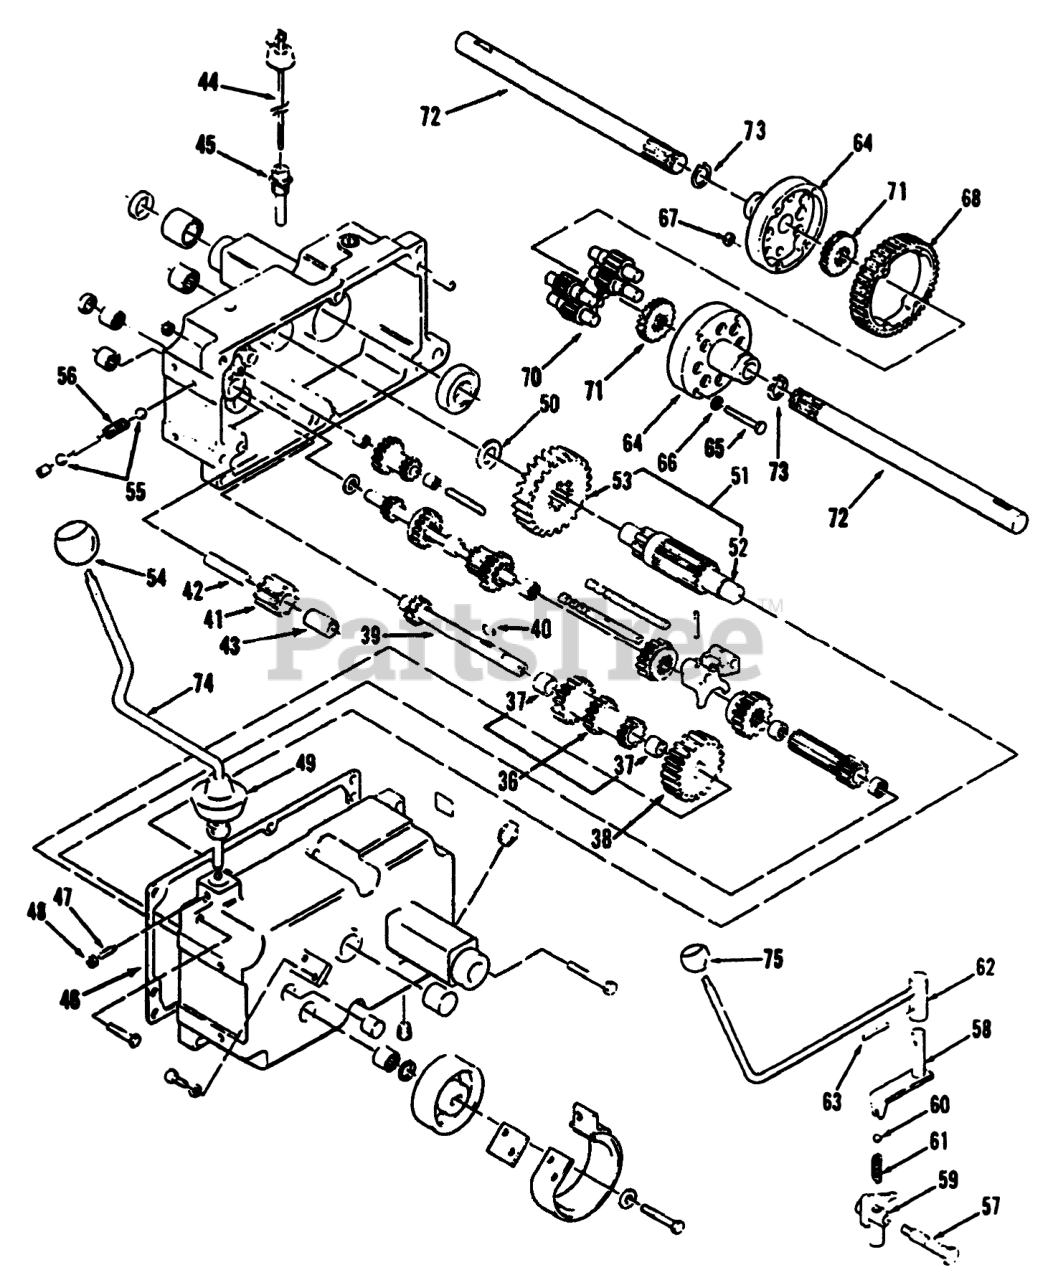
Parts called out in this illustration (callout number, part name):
36	GEAR-CLUSTER
37	BUSHING-BRONZE
38	GEAR-CLUSTER SHAFT
39	Shaft-Cluster
40	KEY-WOODRUFF
41	GEAR/BUSHING ASM-REVERSE IDLER
42	PIN-DIFFERENTIAL
43	BUSHING
44	Dipstick
45	NIPPLE-FILL, TRANSMISSION
46	GASKET-TRANSMISSION
47	SETSCREW
48	NUT-HEX
49	COVER-DUST
50	WASHER-THRUST
51	GEAR ASM
52	PINION SHAFT
55	BALL-DETENT
56	SPRING-SHIFT STOP
57	BOLT-DETENT
58	SHIFT ASM
59	SHIFT FORK ASM
60	BALL-DETENT
61	SPRING-SHIFT STOP
62	SHIFT ROD ASM
63	PIN-SPIROL
64	END CAP-DIFFERENTIAL
65	SCREW-HH
66	WASHER
68	GEAR-DIFFERENTIAL RING, 43T
70	GEAR-PINION, 11T
71	GEAR-AXLE DIFFERENTIAL
72	AXLE-REAR
73	RING-SNAP
74	Shift Lever
75	Knob
